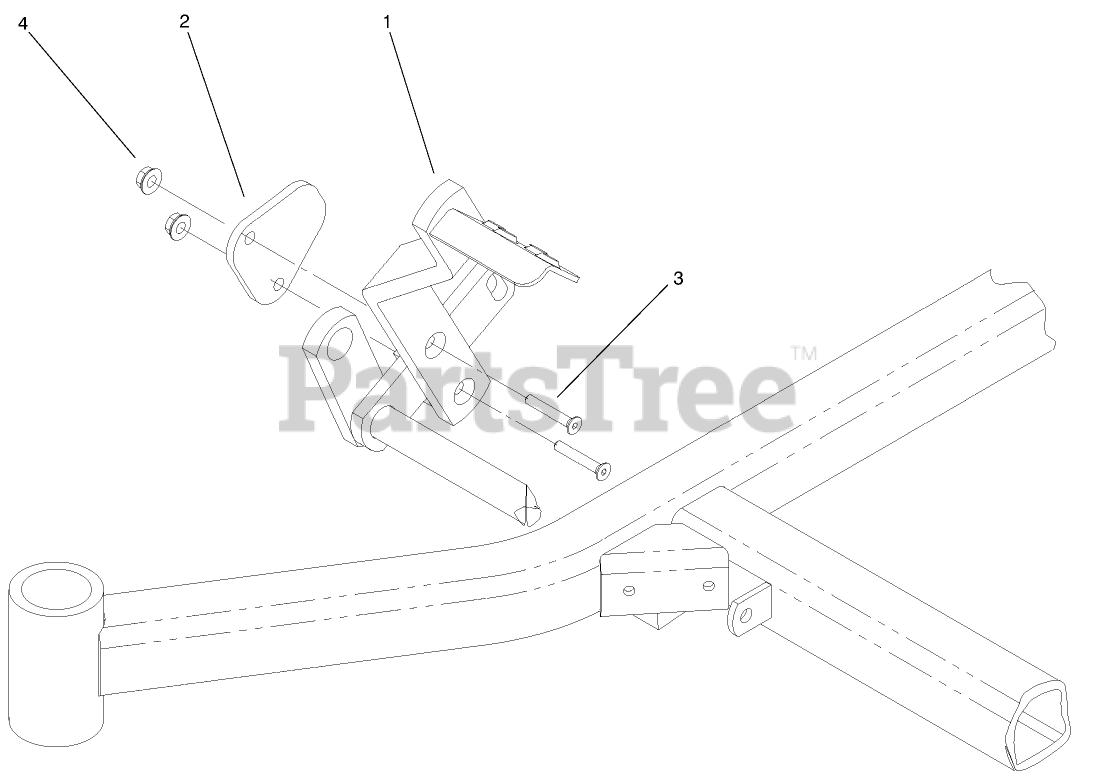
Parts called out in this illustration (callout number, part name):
1	LEVER-LIFT, DECK
2	Strap
3	SCREW
4	NUT-HF
